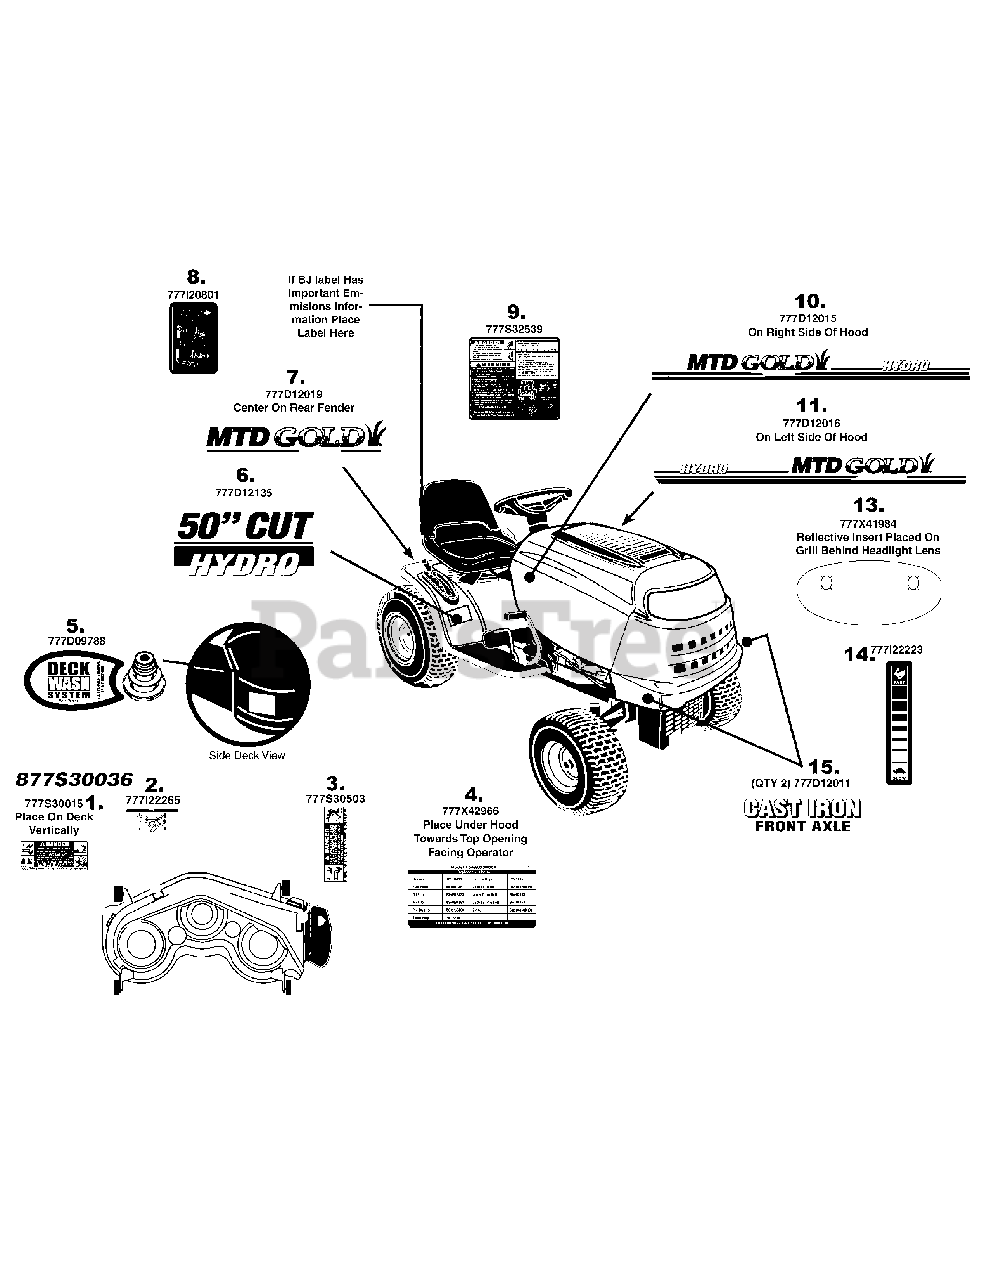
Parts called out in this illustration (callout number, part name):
1	LABEL:RIDER DNGR.STRAIGT
2	LABEL-BELT ROUTE
3	LABEL-DANGER CHUTE
4	LABEL-RIDER PARTS LIST A625P
5	LABEL:RIDER:WHITE
6	LABEL-RIDER 50" HYDRO
7	LABEL-RIDER REAR FENDER MTD GOLD
8	LABEL-HITCHPLATE
9	LABEL:RIDER:SAFETY HYDRO
10	LABEL-RIDER HOOD MTD GOLD HYDRO RH
11	LABEL-RIDER HOOD MTD GOLD HYDRO LH
12	LABEL:RIDER 1&5 STYLE GRILL
13	LABEL-DASH RH
14	LABEL-RIDER LOWER GRILLE CAST IRON
